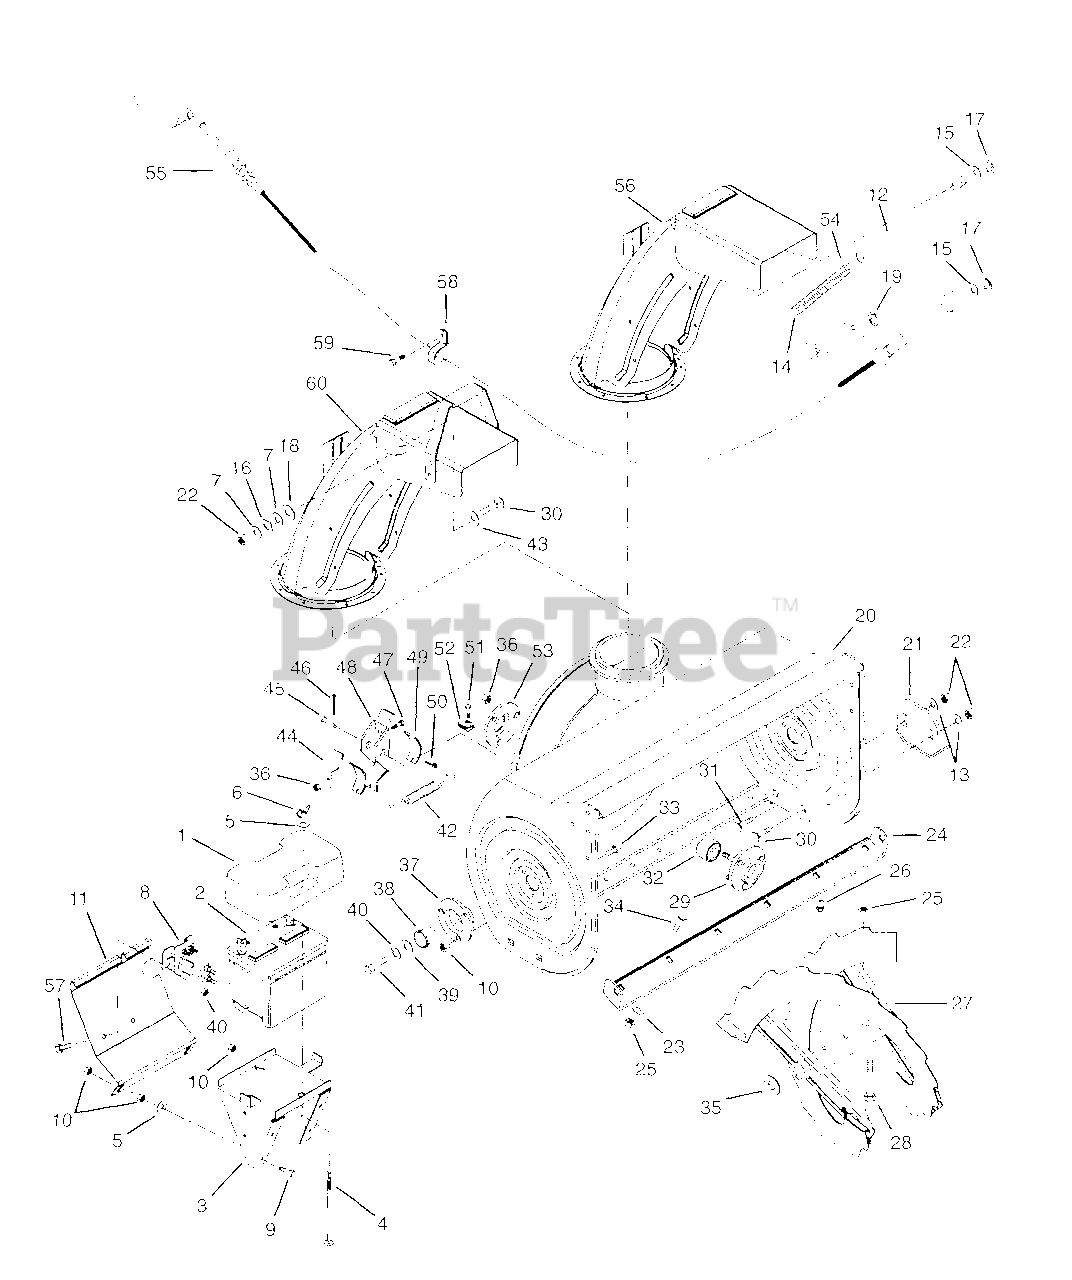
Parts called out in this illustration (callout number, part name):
1	COVER, BATTERY
2	BATTERY
3	TRAY, BATTERY
4	@BLT-RDHDSQNK .25-20X7.00 G2YZ
5	@WSHR-FL-STL.281X.62X.065 YWZC
6	NUT-LK WING .250-20 YWZC
7	@WSHR-FL-STL.406X.812X.065 YWZ
8	SOLENOID
9	@BLT-HEX .25-20X.75 GR5 YWZC
10	@NUT-SPNLK-FLG .25-20 YWZC
11	COVER, SOLENOID - ARIENS
12	ROD, CHUTE
13	@WSHR-FL-STL.438X1.00X.083 YWZ
14	SPRING, COMP. .08 X .40 X 7.15
15	@WSHR-FL-STL.281X.62X.065 YWZC
16	WAVE WASHER .390X.655X.110
17	RG-RTNG-EXT .218X.035 TYPE E
18	WSHR-PLASTIC .390X.875X.062
19	RG-RTNG-EXT .375X.035 TYP E
20	HOUSING, 24" BLOWER
20	HOUSING, 28" BLOWER
20	HOUSING, 32" BLOWER
20	HOUSING, 36" BLOWER
21	RUNNER
21	RUNNER - SKID SHOE
22	@NUT-LK-CTR .38-16 YWZC
23	@WSHR-FL-STL.38X.875X.083 YWZC
24	SCRAPER BLADE 24"
24	BLADE, SCRAPER - 28"
24	BLADE, SCRAPPER - 28"
24	BLADE, 32" SCRAPPER
24	BLADE, SCRAPPER - 36"
25	@NUT-LK-CTR .31-18 YWZC
26	FTG-LUBE .25-28X.256 YWZC
27	RAKE, LEFT-28"(1"ID X 15.75OD)
27	RAKE, RIGHT-28"(1ID X 15.75OD)
27	RAKE, RIGHT-24"(1ID X 14.75OD)
27	RAKE, LEFT-24"(1"ID X 14.75OD)
27	RAKE, LEFT-28"(1"ID X 14.75OD)
27	RAKE, RIGHT-28"(1ID X 14.75OD)
27	RAKE, LEFT-32"(1"ID X 15.75OD)
27	RAKE, RIGHT-32"(1ID X 15.75OD)
27	RAKE, LEFT-36"(1"ID X 15.75OD)
27	RAKE, RIGHT-36"(1ID X 15.75OD)
28	SHEAR BOLT SERVICE ASSEMBLY
29	BEARING FLANGE
30	BLT-RHHDSQSHNK .38-16X.75 G2YZ
31	@BLT-RDHDSHSQNK.38-16X1.0 G5YZ
32	BRG-BALL1.0X2.0X.56
32	BRG-BALL .750X1.750X.50
33	BLT-SERNK SL .25-20X.50 YWZC
34	@BLT-RHDSSQNK .31-18X.62 G5YZ
35	WSHR-FL-STL 1.010X1.505X.062YZ
36	@NUT-LK-CTR .25-20 YWZC
37	BEARING SUPPORT
38	BSHG-FLG 1.000X1.12X.62X1.50BR
39	WSHR-FL-STL.511X1.441X.125 YWZ
40	WSHR-LK .500X.151 HVY YWZC
41	@BLT-HEX .50-13X1.00 GR5 YWZC
42	SG-TENS .062X.56X8.0 WLD 11
43	WSHR-FL-STL .52X.827X.062 YWZC
44	ARM EXTENSION
45	PIN-CLEV .371X1.16 YWZC
46	@PIN-CTR .06X.75 EXTPRSQCT YWZ
47	@BLT-HEX .25-20X.75 GR5 YWZC
48	BRAKE ARM ASSEMBLY
49	BRAKE LINING
50	RVT-TBLR .187X.437 RH ST PL
51	BLT-SERHFWH .38-16X.75 YWZC
52	NUT-RETNR .38-16 TINRMAN
53	BEARING FLANGE
54	@WSHR-FL-STL.344X.688X.065YWZC
55	CABLE-DEFLECTOR CONTROL
56	CLEVIS PIN
57	@PIN-CTR .06X.50 EXTPRSQCT YWZ
58	CLAMP, CUSHIONED STEEL
59	@BLT-HEX .38-16X.75 GR5 YWZC
60	CHUTE, DISCHARGE W/CAP & DECAL
61	CHUTE, DISCHARGE W/CAP & DECAL
62	@BLT-HEX .25-20X.50 GR5 YWZC
